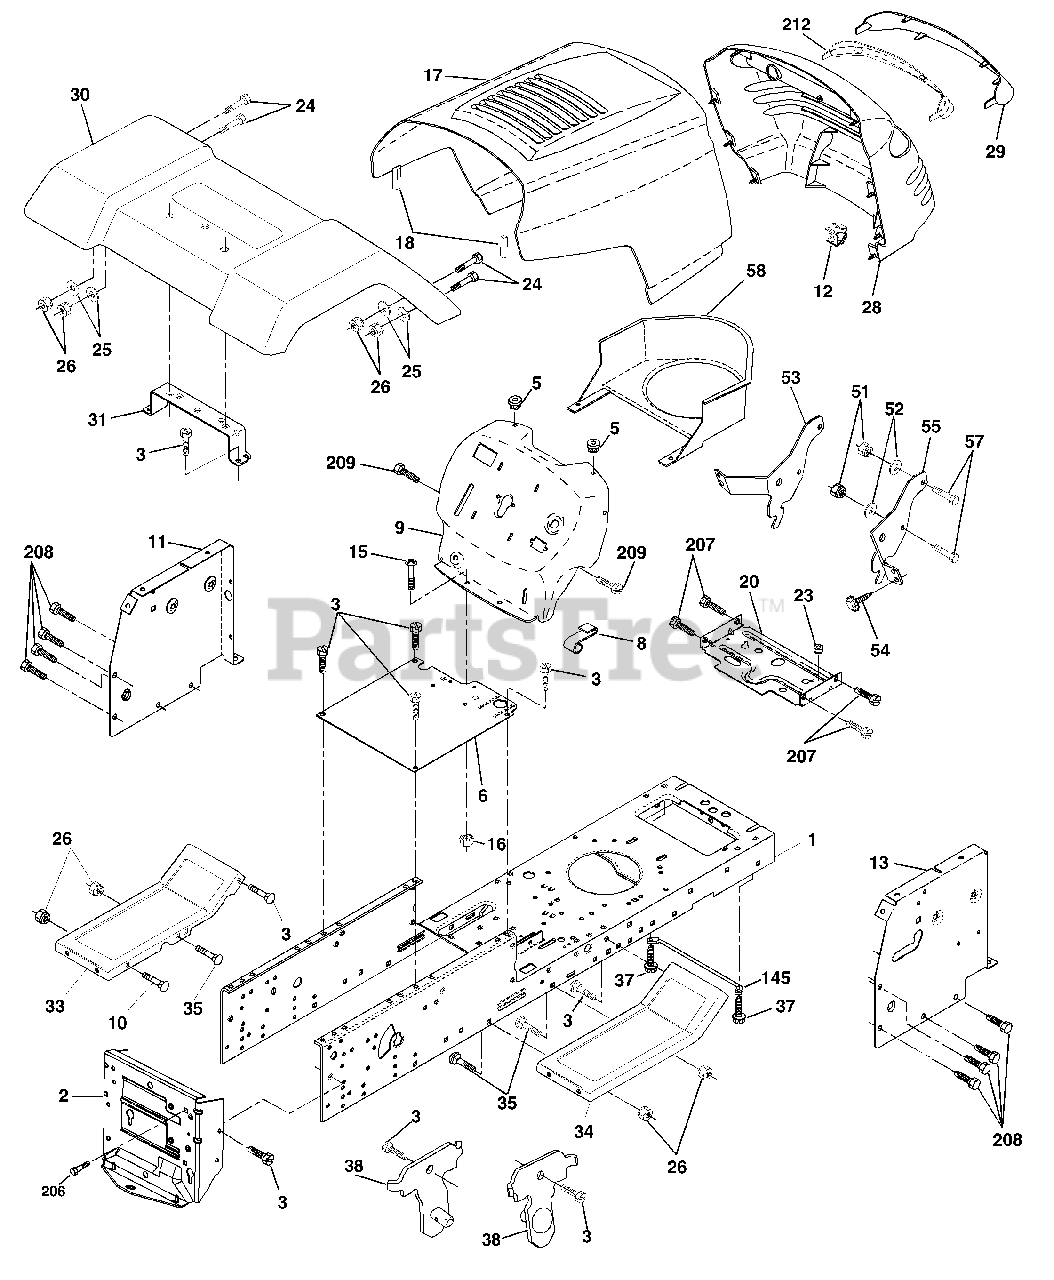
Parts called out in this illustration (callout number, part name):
2	Drawbar
3	Screw 3/8-16 x 3/4
5	Bumper Hood/Dash
6	Saddle Flat Lt Fender Shift
8	Clip Retainer Slide-On
9	Dash
10	Bolt Rd Hd Sqnk. 3/8-16 Unc x 1
11	Panel Asm. Dash Lh
12	Clip Tinnerman Grile P/L
15	Screw Mach Trhd 5/16-18 Unc x 3/4
16	Nut Keps 5/16-18 Unc
17	Hood
18	Bumper Hood
20	Plate Mtg Battery/Fuel Tank Fr
23	Bushing Snap Nyl Blk Fuel Line
24	Bolt Fin Hex 3/8-16 Unc x 1 Gr. 5
25	Washer 13/32 x 13/16 x 12 Ga.
26	Nut Lock Hex w/Insert 3/8-16 UNC
28	Grill/Lens Asm
29	Lens Grille Private label
30	Fender Asm
31	Bracket Fender
33	Footrest Lh
34	Footrest Rh
35	Bolt Rd Hd Sht. Sqnk. 3/8-16 x 3/4
37	Screw Thdrol 5/16-18 x 1/2 Tyt
38	Bracket Asm. Pivot Mower Rear
51	Nut Lock Hex W/Ins. 1/4-20
52	Washer 9/32 x 7/8 x 16 Ga.
53	Bracket Grille LH
54	Screw Hex Wshd 8-18 x 7/8
55	Bracket, Grille RH
57	Bolt Fin Hex 1/4-20 x .75
58	Air Duct Private Label
145	Rod Pivot Chassis/Hood
206	Bolt shoulder 5/16-18
207	Screw Thdrol 5/16-18 x 1/2
208	Screw Thdrol 3/8-16 x 1/2
209	Screw Hex Wsh Thdrol 3/8-16
212	Insert Lens Reflector
